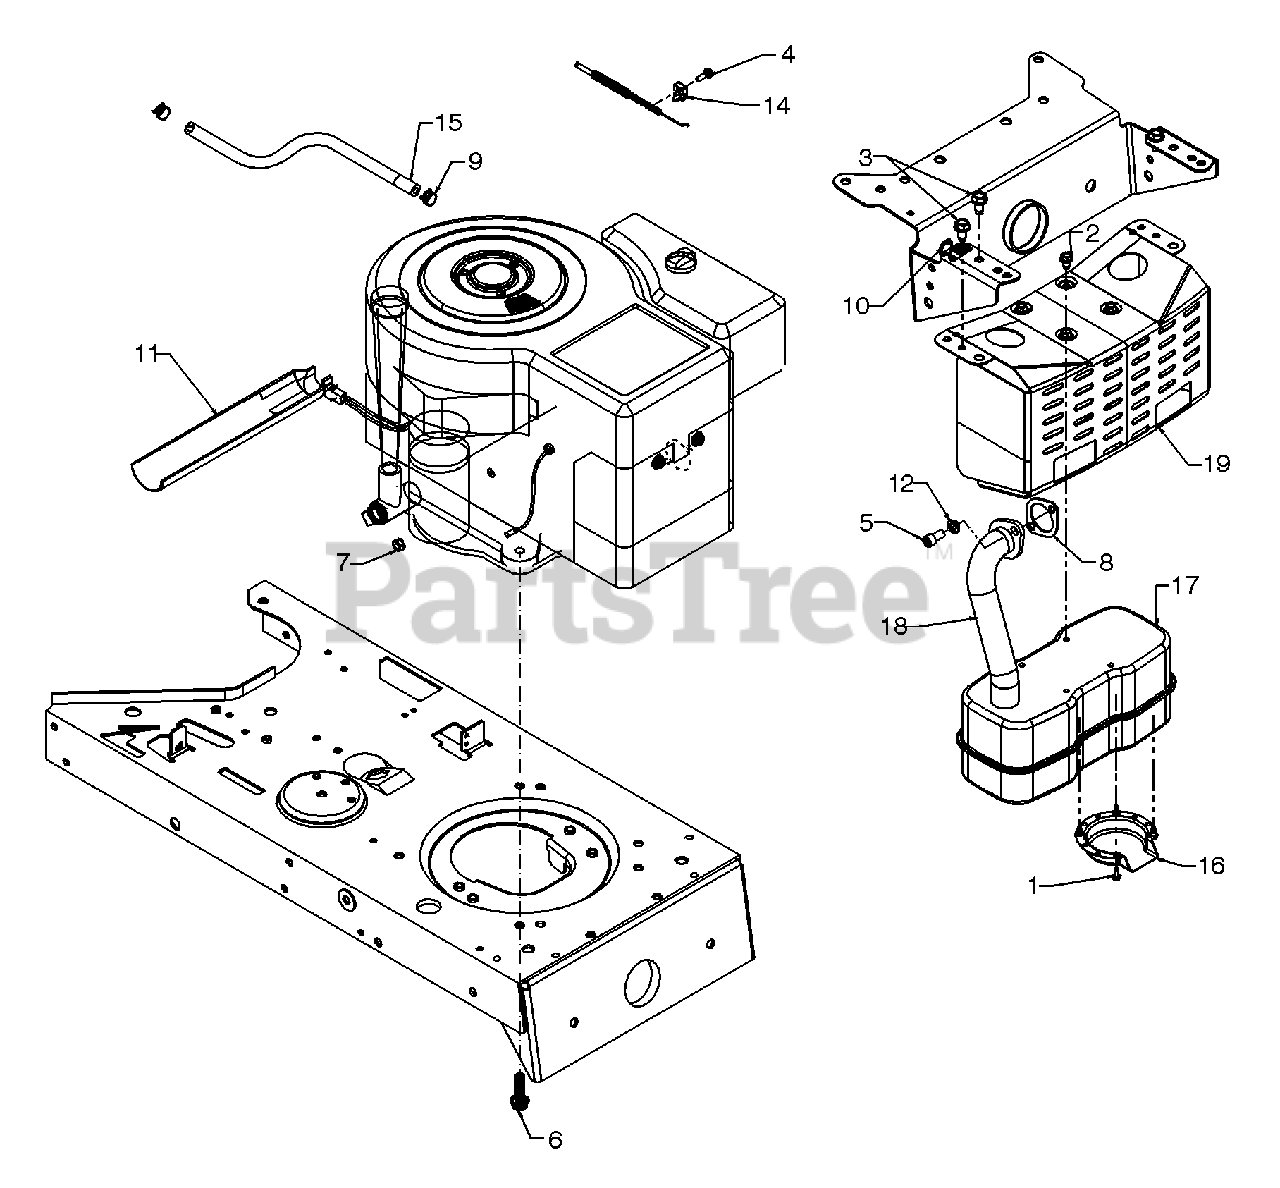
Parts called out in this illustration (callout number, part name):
1	Hex Slot Scr. #8-32 x .38" Lg.
2	Hex Wash. TT-Tap Scr. 1/4-20 x .5" Lg.
3	Hex Wash Hd. TT-Tap Scr. 5/16-18 x .62"
4	Scr. #10-32:.620 Hx. Slot Wash.
5	Socket Hd. Bolt 5/16-18 x .62" Lg.
6	Scr. 3/8-16 x 1.25
7	Nut, Hex 1/4-20
8	Exhaust Gasket
9	Hose Clamp .49 Dia.
10	Clamp 9/16 Dia.
11	Oil Drain Sleeve
12	L-Wash. 5/16" I.D.
14	Casing Clamp, Throttle, B&S
15	Fuel Line Hose
16	Muffler Deflector
17	Muffler
18	Exhaust Pipe
